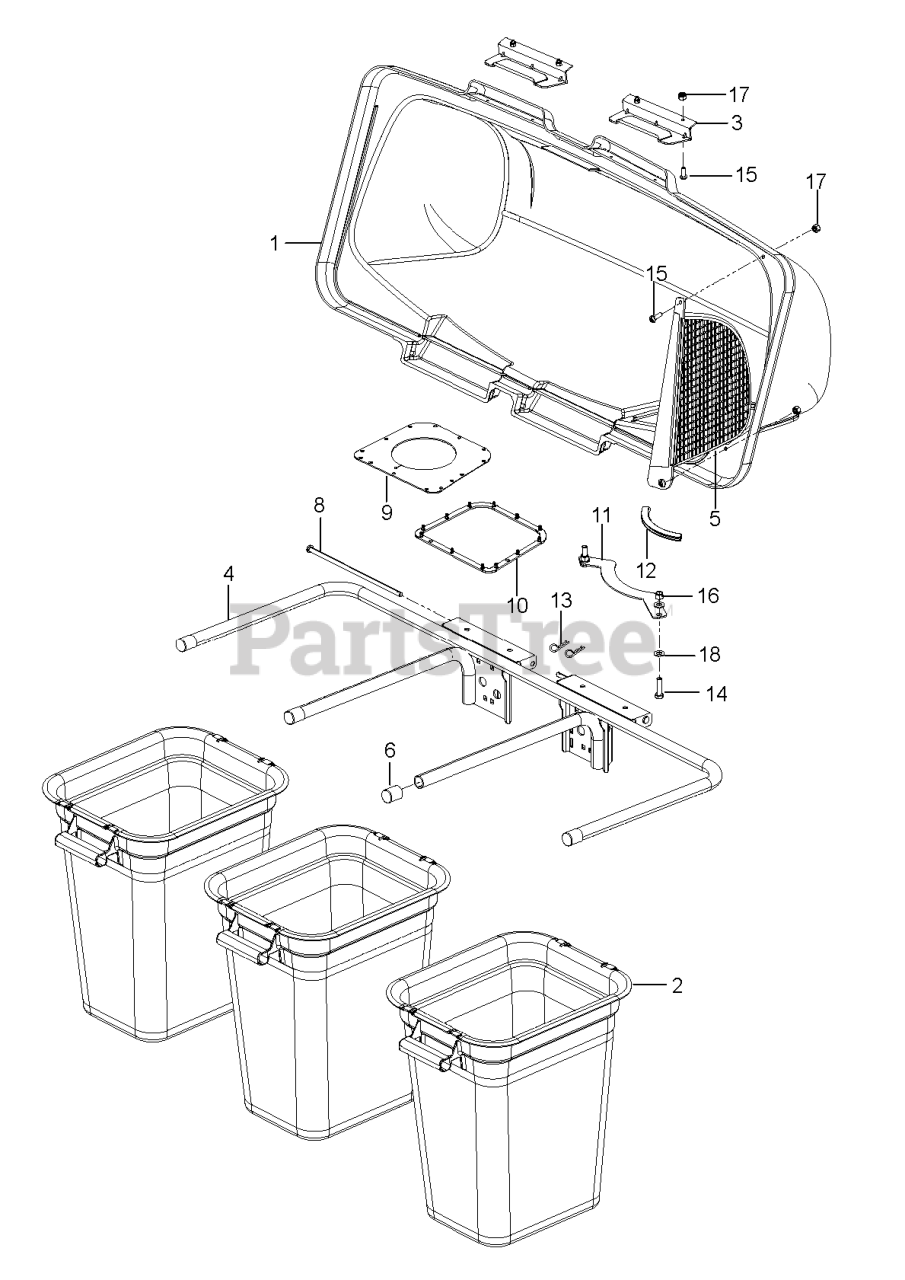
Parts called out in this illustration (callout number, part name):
1	COVER.ASM.3BIN.GENERIC.
2	CONTAINER BAG, SOFT
3	LATCH CER38
4	BAGGER, FRAME
5	SCREEN.COVER.BAGGER
6	TUBING PLUG
8	BAGGER.HINGE.PIN
9	SEAL.BAGGER.TOP.3-BIN.BLK
10	GASKET.COVER.BAGGER
11	SUPPORT.CHUTE.COLLECTION.BLACK
12	RP.FLEX TRIM, BLK-LENGTH 1 FT
13	RETAINER SPRING
14	BOLT.5/16-18X1-1/4 FULL.THREAD
15	SCREW #10-24 X 5/8
16	5/16-18 NYLOC FLANGE NUT
17	NUT 10-24 NYLOC
18	WASHER
